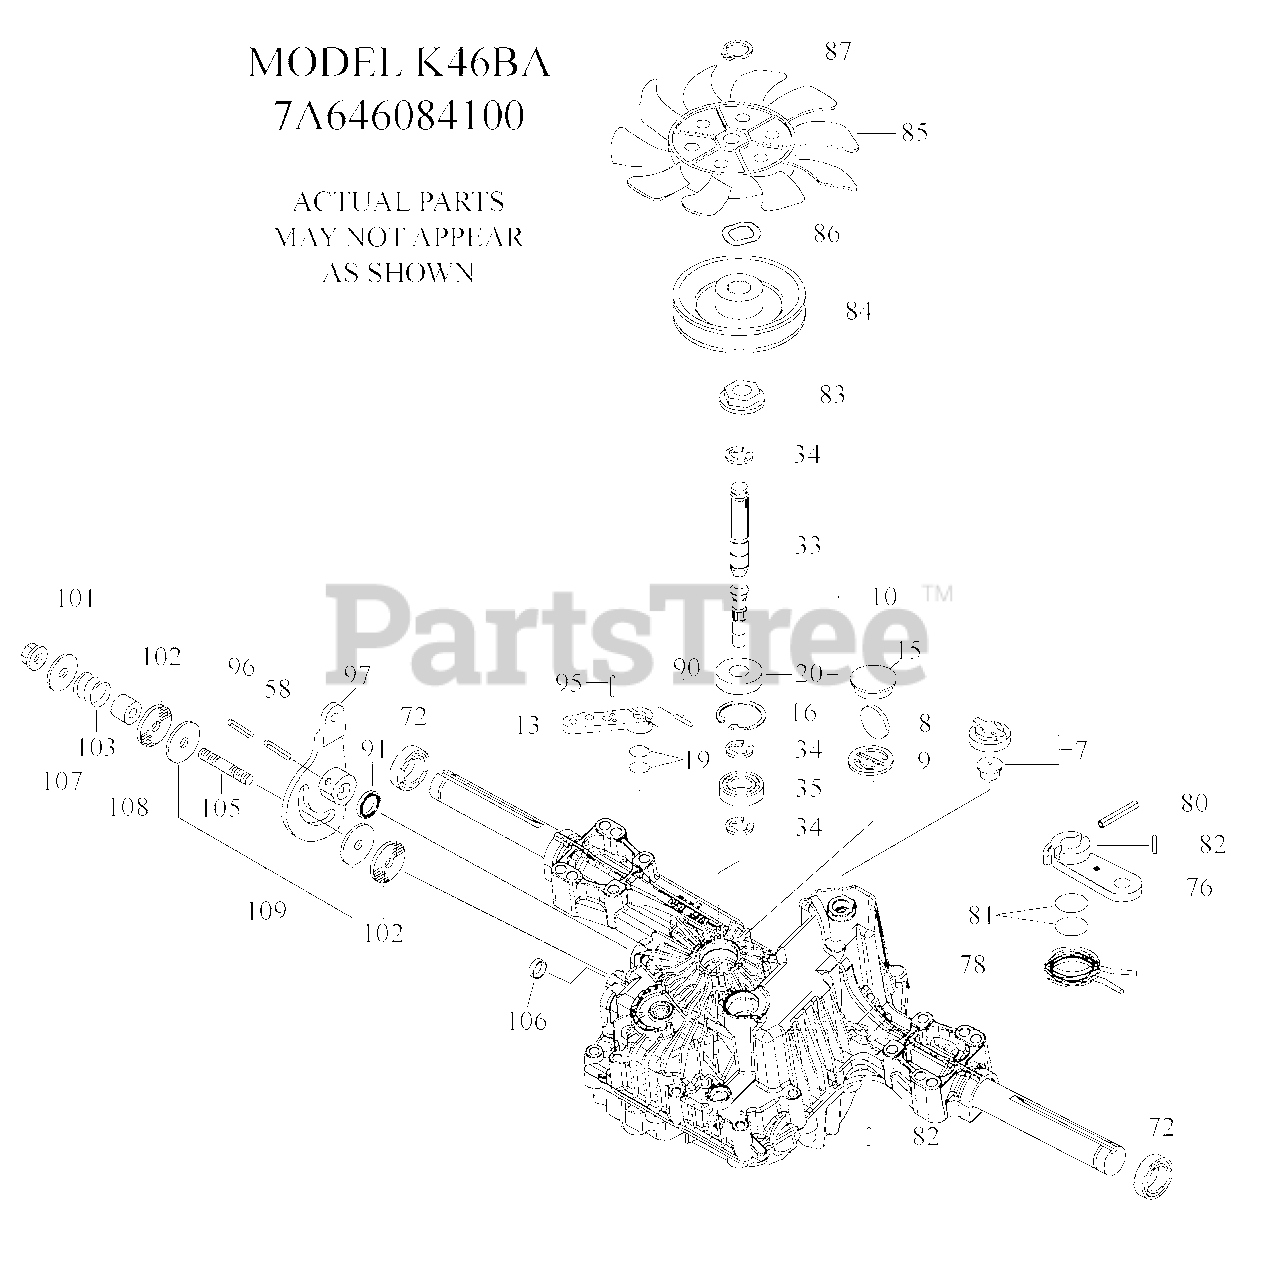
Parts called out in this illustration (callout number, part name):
7	Vent Valve 15
8	Magnet
9	Magnet Holder
10	Pump Shaft/Bearing Kit
13	Bypass Lever
15	Sealing Cap 30
16	Snap Ring C 35
19	O-Ring 1a P10a
20	Seal Tc 153507
33	Pump Shaft (Standard
35	Bearing 6202c3
58	Roll Pin 6 x 40
72	Seal 19 x 32 x 8
76	Brake Lever
78	Brake Return Spring
80	Spring Pin 5 x 32
81	O-Ring 1a P12
82	Spring Pin 4 x 16
83	Spine Collar
84	Pulley L
85	Fan, Black
86	Wave Washer
87	Snap Ring
90	Spring Pin 3.0a x 20
91	Oil Seal 16 x 22 x 03
95	Spring Pin 3.0a x 16
96	Roll Pin 3.5 x 40
97	Control Lever
101	Lock Nut 10
102	Washer 10 x 40 x 4
105	Stud 10 x 60
106	Sealing Cap 18
107	Washer 10 x 36 x 2.8
108	Collar 10 x 20 x 17
109	Friction Plate Kit
